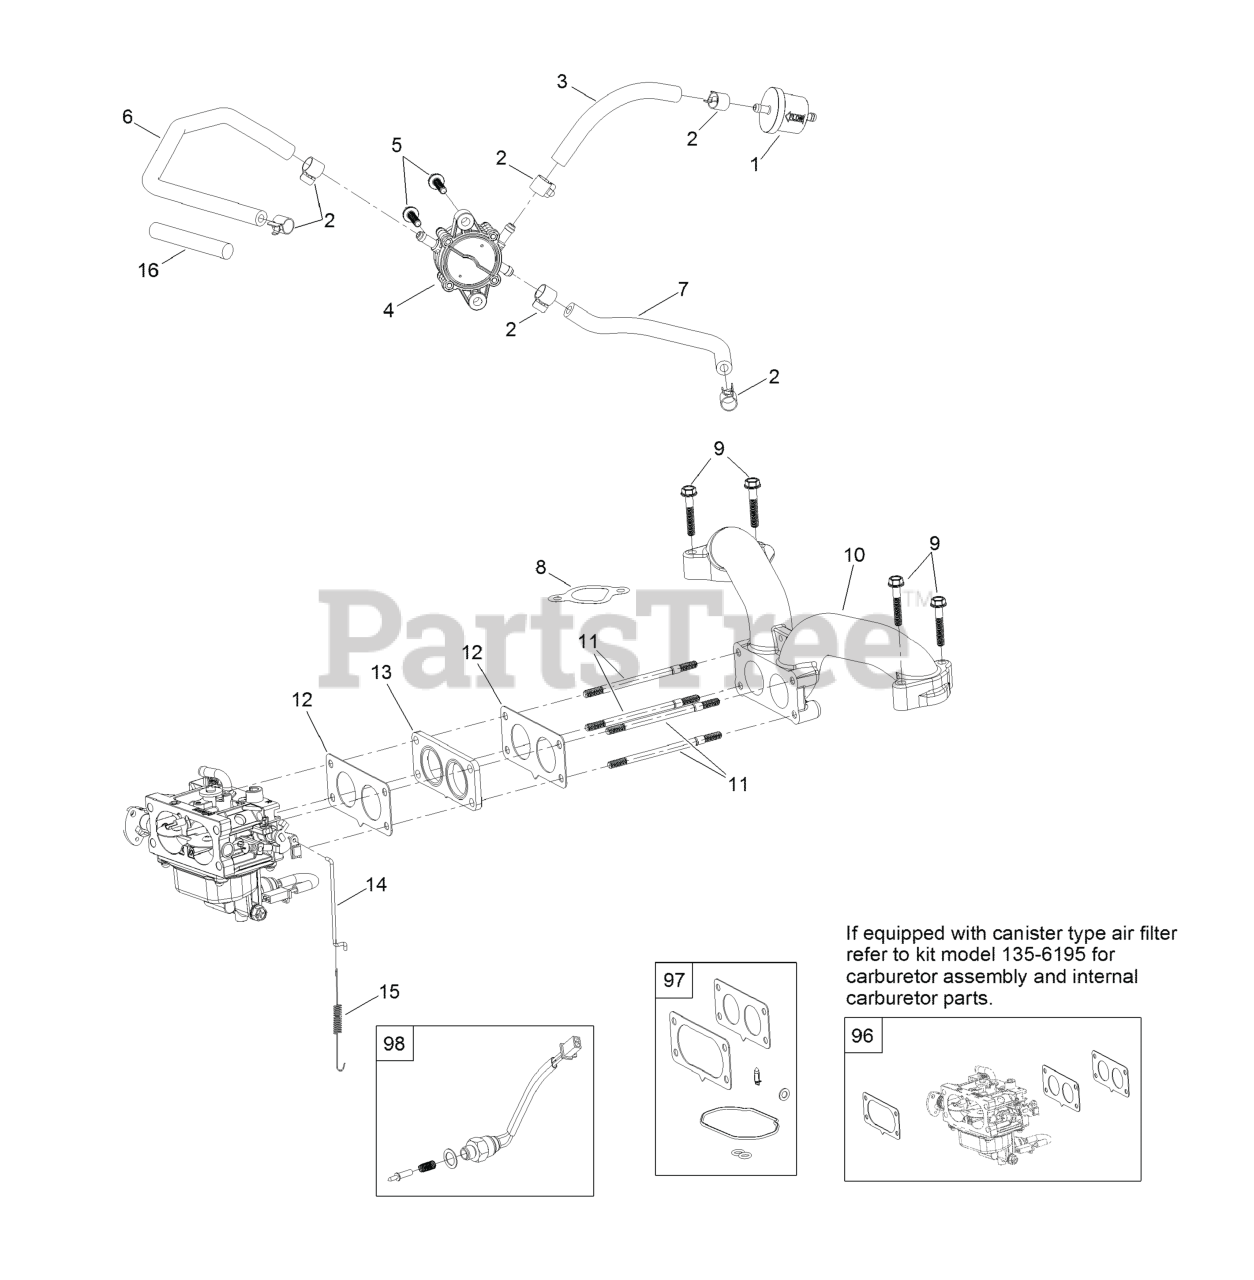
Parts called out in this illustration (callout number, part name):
1	FILTER-FUEL
2	CLAMP-FUEL LINE
3	LINE-FUEL
4	PUMP-FUEL
5	SCREW-HHF
6	HOSE-FUEL
7	HOSE-FUEL
8	GASKET-INTAKE
9	SCREW-HHF
10	MANIFOLD-INTAKE
12	GASKET-CARBURETOR
13	INSULATOR-CARBURETOR
14	LINKAGE-THROTTLE
15	SPRING-RETURN, THROTTLE
16	SLEEVE-FUEL LINE PROTECTO
96	CARBURETOR REPLACEMENT KI
97	CARBURETOR REPAIR KIT
98	SOLENOID KIT
